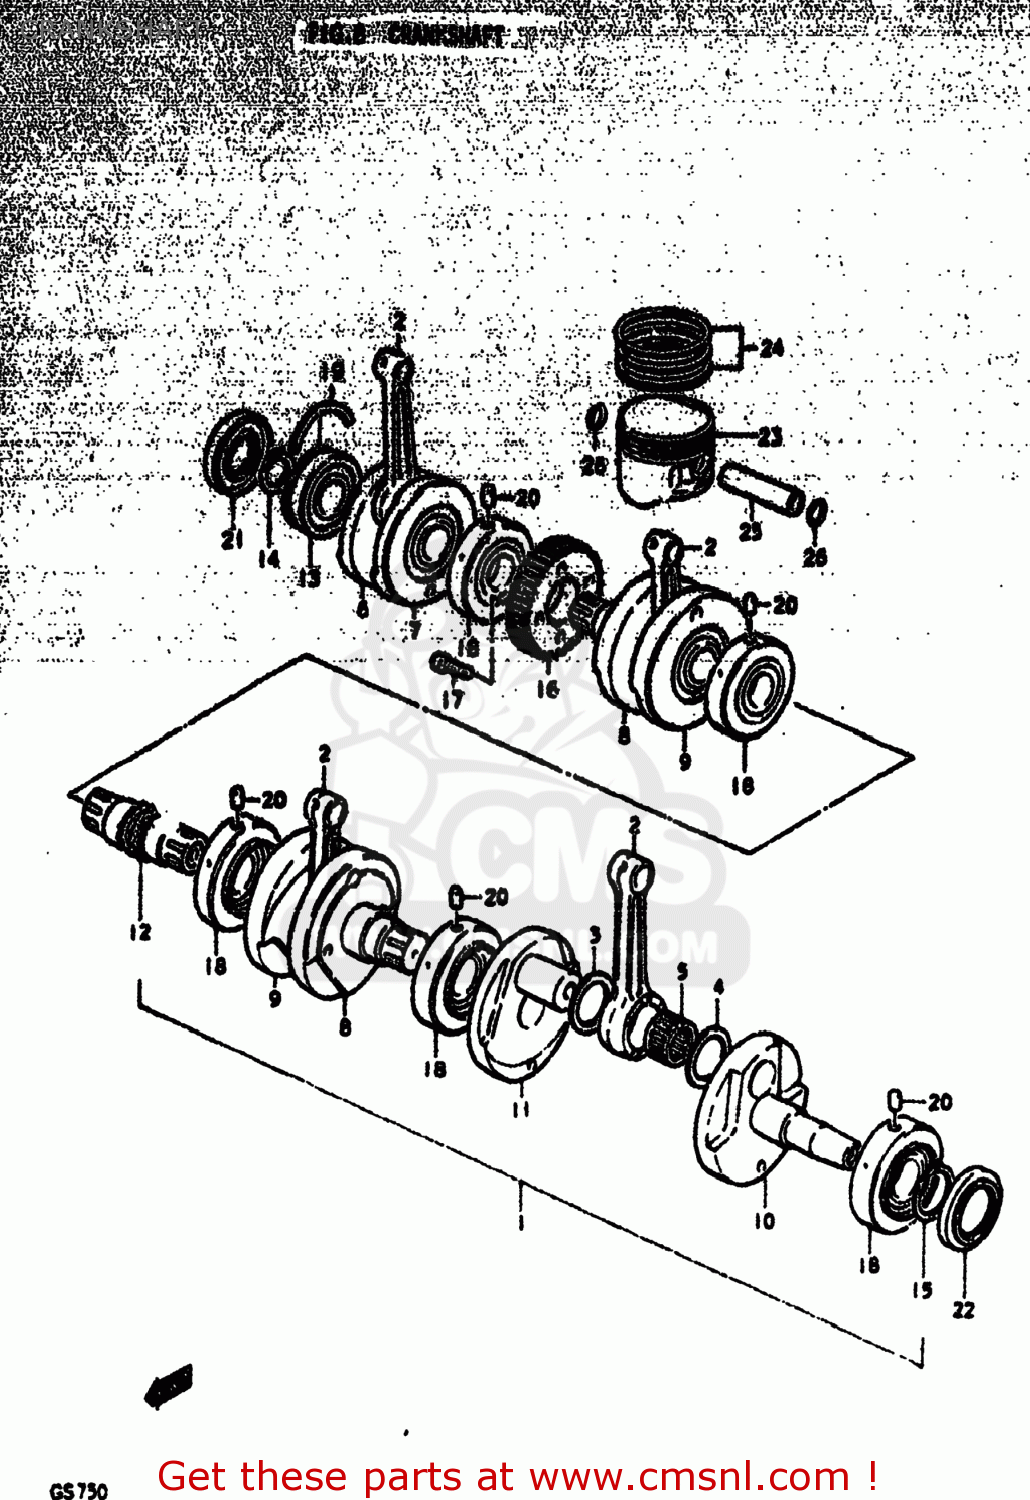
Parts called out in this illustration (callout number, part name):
1	CRANKSHAFT ASSEMBLY
2	CONNECTING ROD
3	WASHER (28X48X2)
4	WASHER(28X48X1)
5	BEARING(28X38X19.8)
6	CRANKSHAFT
7	WEB,CRANK
8	CRANKSHAFT
9	WEB,CRANK,MIDDLE
10	CRANKSHAFT,LEFT
11	WEB,CRANK
12	SHAFT,TIMING CHAIN DRIVE
13	BEARING(30X72X19)
14	CIRCLIP,30MM
15	CIRCLIP.32MM
16	GEAR,PRIMARY DRIVE
17	BOLT
18	BEARING
19	C RING
20	PIN
21	SEAL,OIL(30X72X11)
22	OIL SEAL
23	PISTON
24	RING SET,PISTON
25	PIN,PISTON
26	CIRCLIP
